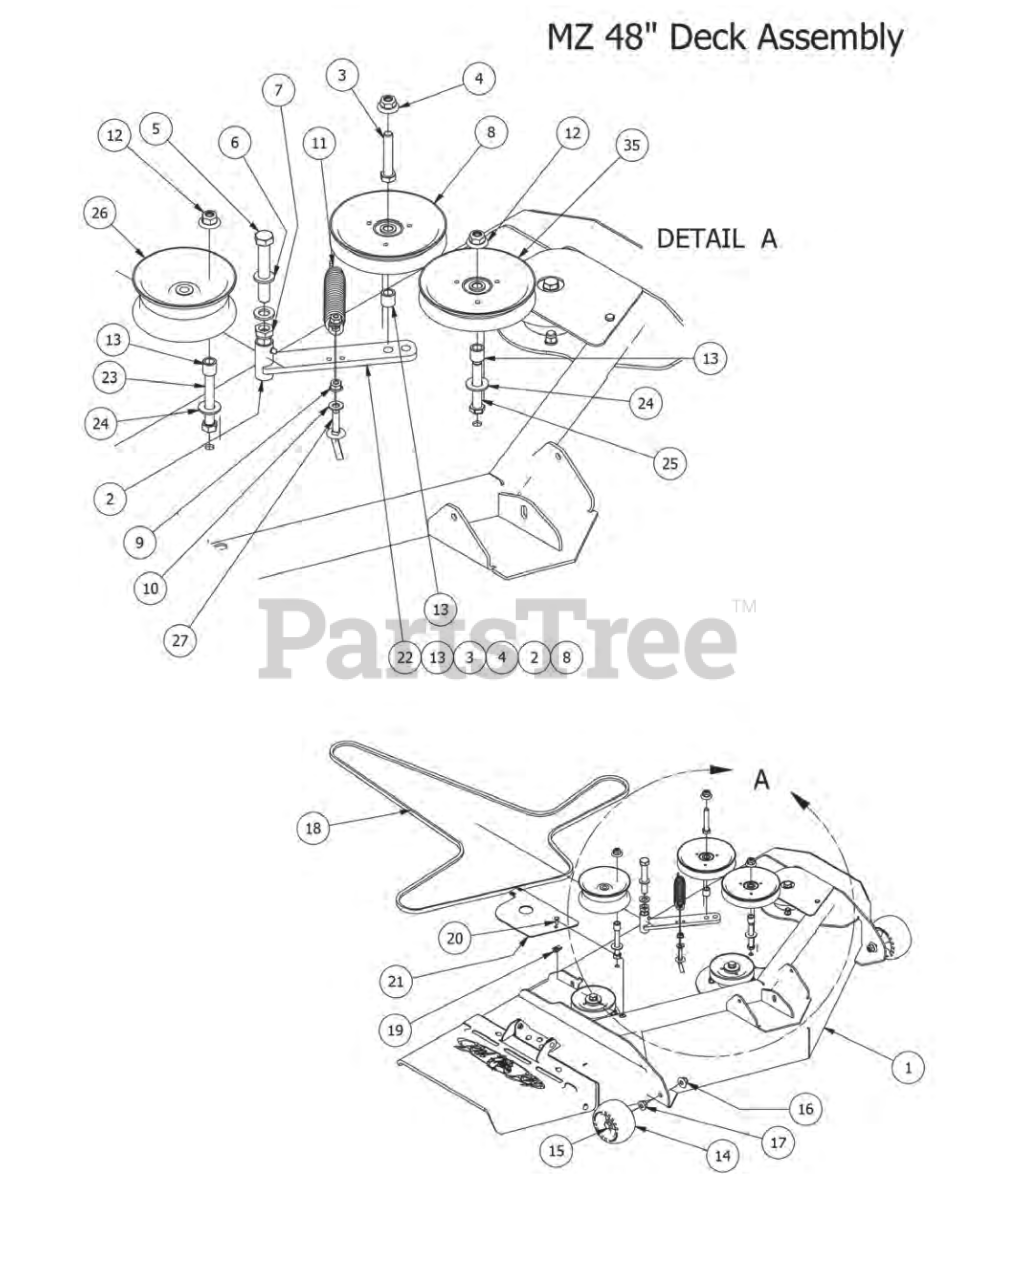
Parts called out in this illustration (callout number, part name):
1	48 MZ Deck
2	Deck Idler arm
3	1/2" x 2 3/4" Hex Bolt
4	1/2-13 Nylon Flange Nut-Orange
5	5/8" x 4" Hex Bolt
6	.635 ID Plastic Washer
7	5/8-11 Nylon Insert Jam Half Nut
8	5-3/4 Idler Pulley
9	3/8" Nylock Flange Nut
10	3/8" Flat Washer
11	Deck Idler Spring
12	1/2-13 Nylon Flange Nut-Orange
13	3/4 OD x 1/2 ID x 3\4 Length
14	Deck Wheel
15	1/2 x 3 1/2 Flange Bolt Grade 8
16	1/2-13 Nylon Flange Nut-Orange
17	1/2-13 Hex Flange (GR.G) ZC
18	B128 Deck Belt
19	1/4-20 Cage Nut
20	1/4" x 3/4" Hex Bolt
21	MZ Pulley Cover 48"
22	Parts 2,3,4,8,13 make up the deck idler assembly
23	1/2-13 x 3 1/2 GR 5 Hex Bolt
24	1/2" Washer (Grade 8)
25	1/2-13 x GR 5 Hex Bolt Zinc
26	5 3/4" Deck Idler Pulley
27	3/8 x 1-1/2 Carriage Bolt
